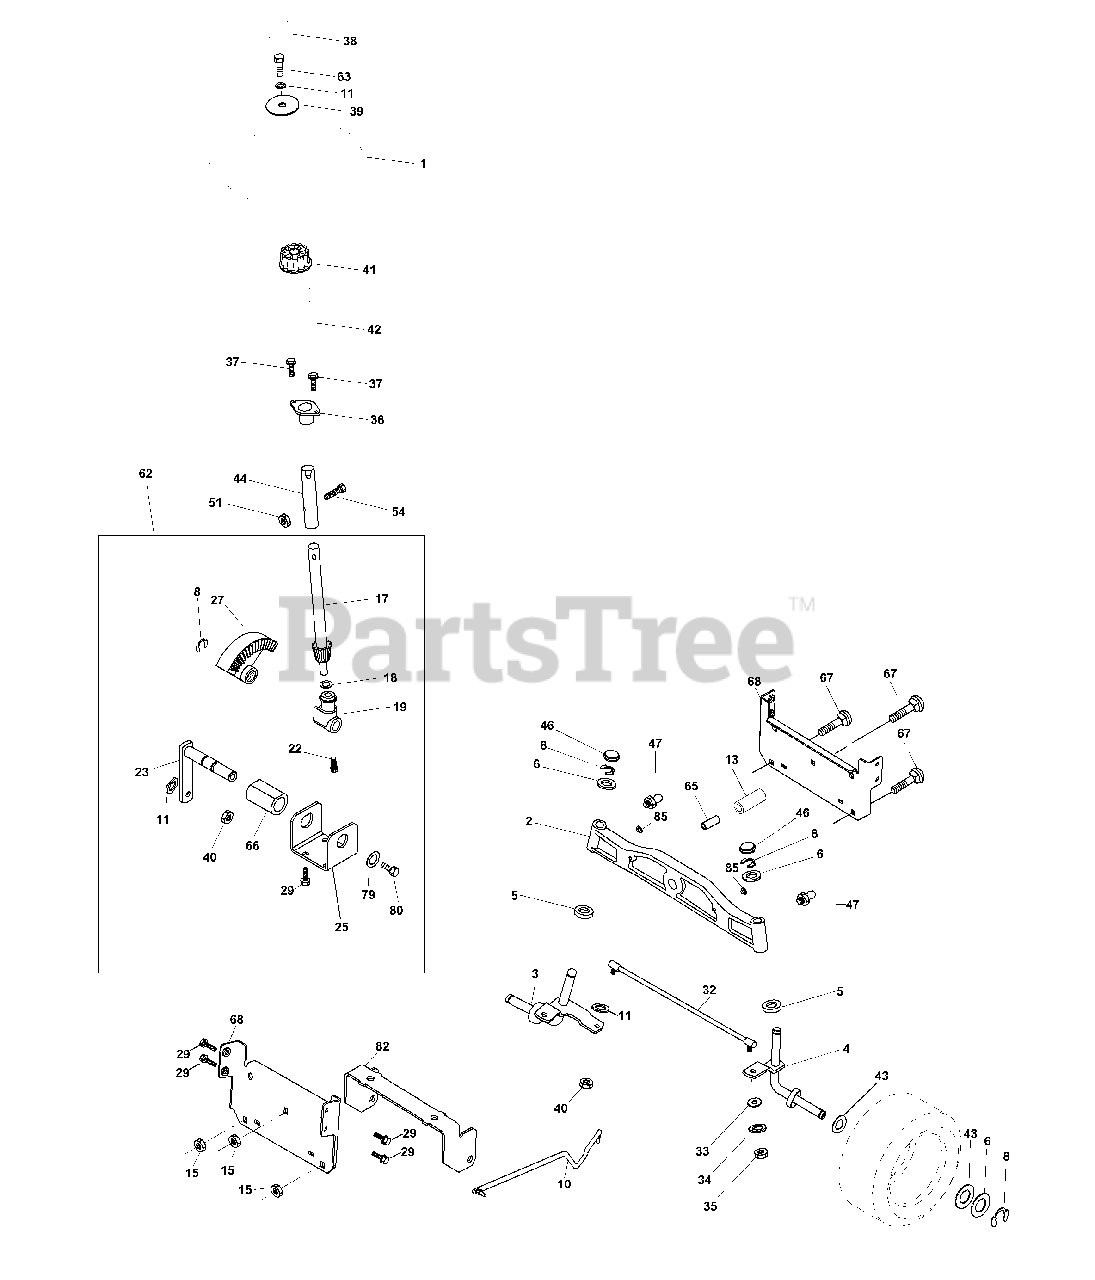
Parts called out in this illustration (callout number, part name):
1	Wheel Steering
2	Axle Asm Stmp Dropped STLT
3	Spindle Asm LH
4	Spindle Asm RH
5	Bearing Race Thrust Harden
6	Washer 25/32 X 1-5/8 X 16 Ga
8	Ring Klip #t5304-75
10	Link Drag
11	Washer Lock Hvy Hlcl Spr 3/8
13	Spacer Brg. Axle Front
15	Nut Hex Flange Lock
17	Shaft Asm Strg
18	Washer Thrust 515x 750x 033
19	Support Shaft
22	Screw Hex Wsh Hd Torx
23	Shaft Asm Pittman
25	Bracket Steering
27	Gear Sector
28	Washer 13/32 x 7/8 x 16 Ga.
29	Screw 3/8-16x.75
32	Rod Tie
33	Washer 11/32 x 3/4 x 16 Ga.
34	Washer Lock Hvy Hlcl Spr 5/16
35	Crownlock Nut 5/16-24
36	Bushing Strg
37	Screw
38	Insert Cap Strg Wh Au
39	Washer 13/32 X 2-3/8 X 12 Ga
40	Lock nut
41	Adaptor Wheel Strg
42	Boot Steering Dash
43	Washer 25/32 X 1 1/4 X 16 Ga
44	Extension Steering Shaft LR/LT
46	Cap Spindle Fr Top Blk
47	Fitting Grease
51	Nut Lock Hex w/Ins 5/16-18
54	Bolt Fin Hex 5/16-18 Unc x 1-1/4
62	Kit, Steering Assembly Svc
63	Bolt Fin Hex 3/8-16unc x 1 Gr. 5
65	Brace Axle
66	Bearing Arm Pittman
67	Bolt Rdhd Sq 3/8-16 Unc x 2-1/4
68	Axle, Brace
79	Washer 13/32 x 1-1/4 x 12 Ga.
80	Bolt Hex Nylon 3/8-16 x 3/4
82	Bracket Susp. Chassis Front
85	Fastener Christmas Tree
